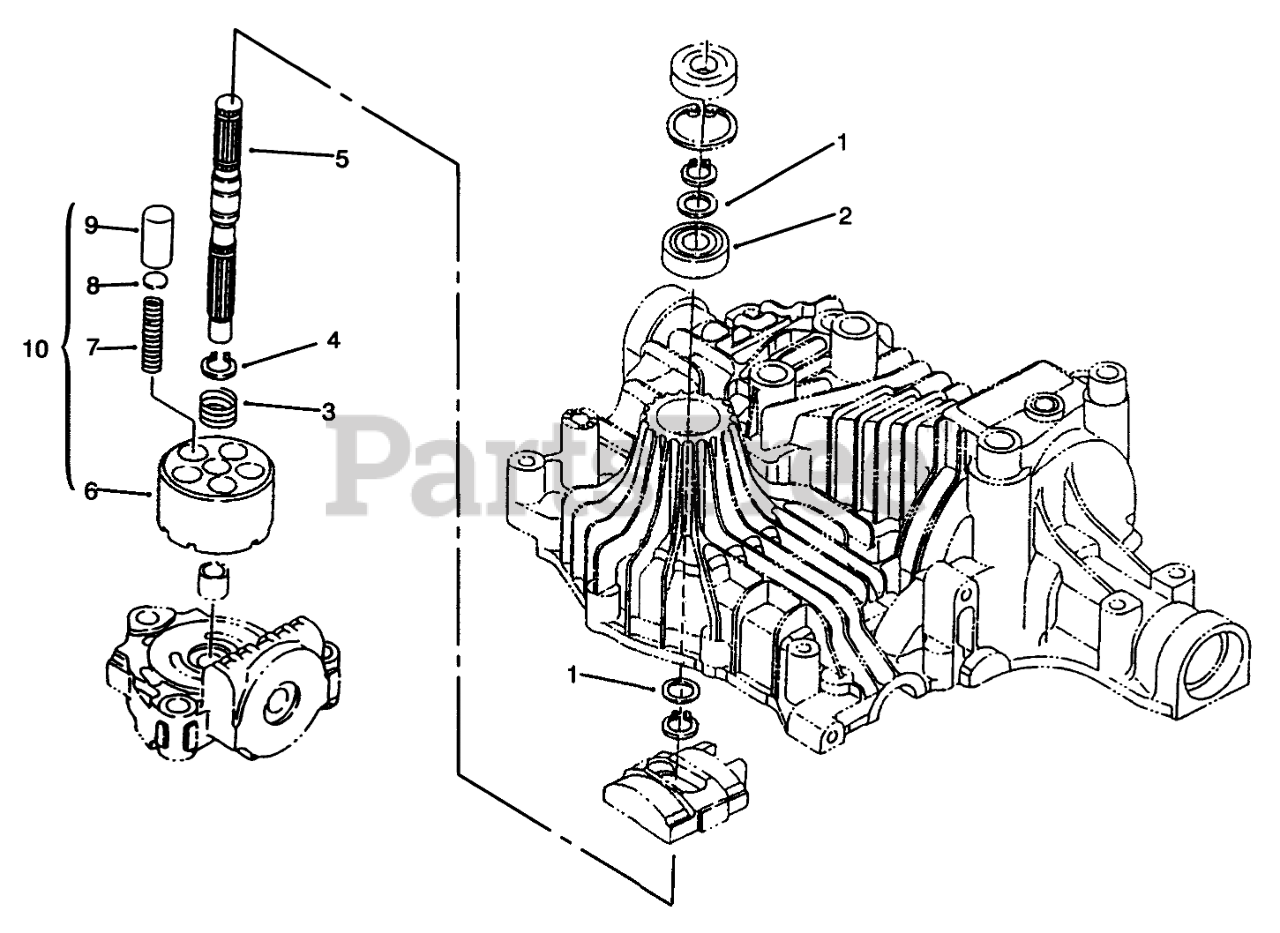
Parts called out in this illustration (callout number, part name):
1	WASHER
2	BEARING-BALL
3	SPRING
4	RING-SNAP
5	SHAFT - PUMP
6	Block Cylinder
8	Washer
10	ASM - CYCLINDER INC 6-9
